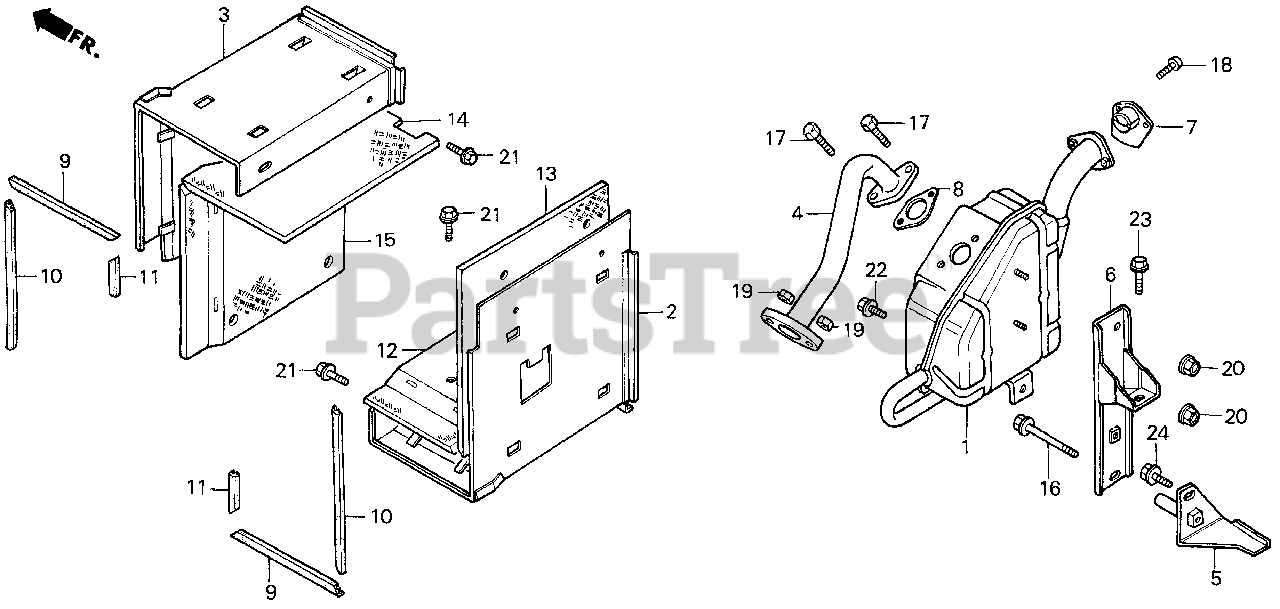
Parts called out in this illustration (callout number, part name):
2	DUCT, MUFFLER (LOWER)
3	DUCT, MUFFLER (UPPER)
5	BRACKET, MUFFLER STAY SETTING
6	STAY, MUFFLER
7	ARRESTER, SPARK
8	GASKET, MUFFLER
9	SEAL A, MUFFLER DUCT
10	SEAL B, MUFFLER DUCT
11	SEAL C, MUFFLER DUCT
12	INSULATOR A, MUFFLER DUCT (LOWER)
13	INSULATOR B, MUFFLER DUCT (LOWER)
14	INSULATOR A, MUFFLER DUCT (UPPER)
15	INSULATOR B, MUFFLER DUCT (UPPER)
16	BOLT, FLANGE (8X70)
17	BOLT, HEX. (8X20)
18	SCREW, PAN (5X10)
19	NUT, HEX. (8MM)
20	NUT, FLANGE (6MM)
21	BOLT, FLANGE (6X10)
22	BOLT, FLANGE (6X12)
23	BOLT, FLANGE (8X16)
24	BOLT, FLANGE (8X16)
